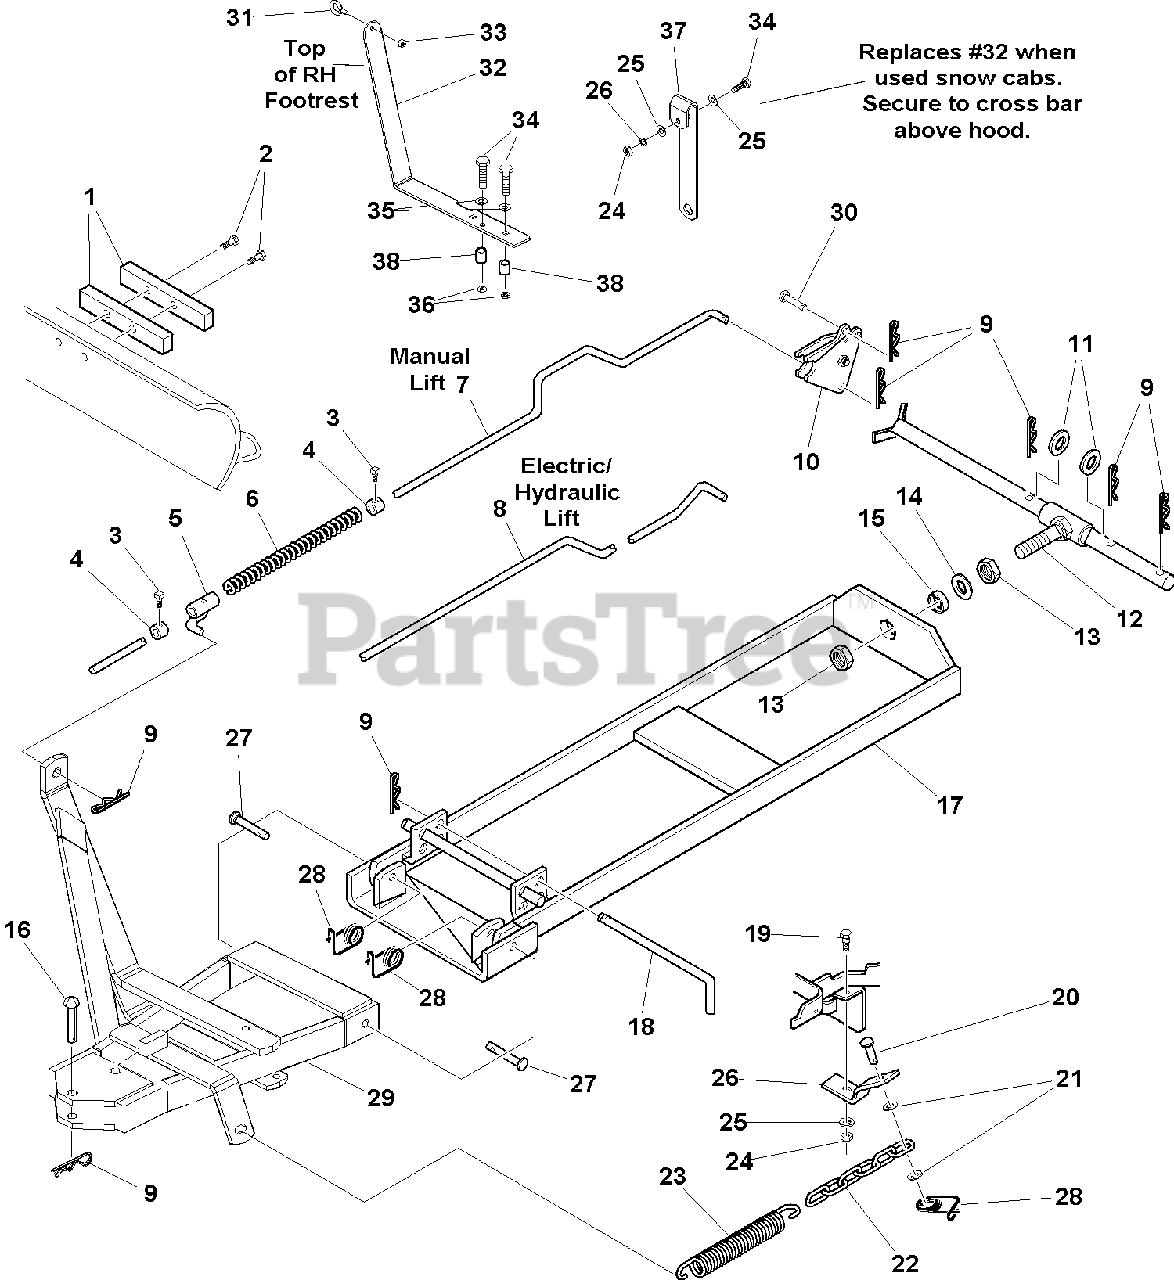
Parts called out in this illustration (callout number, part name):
1	BAR
2	CAPSCREW, Taptite, 5/16-18 x 1
3	SCREW, Set, 5/16-18 x 1/2
4	COLLAR
5	GUIDE ASSEMBLY
7	ROD, Manual Lift
8	ROD, Eletric / Hydraulic Lift
10	EXTENSION ASSEMBLY KIT
11	WASHER, 3/4
12	TUBE & BOLT ASSEMBLY
13	NUT, Hex, 5/8-11
14	WASHER, 5/8
17	REAR PUSH BAR ASSEMBLY
19	CAPSCREW, Hex Head 5/16-18 x 1
20	PIN
21	WASHER, 5/16
22	CHAIN, Link
24	NUT, Hex, 5/16-18
25	LOCKWASHER, 5/16
26	BRACKET
27	PIN
28	RETAINER, Pin
29	PUSH BAR ASSEMBLY
30	PIN, Round Head, 1/2 x 2-1/2
33	LOCKNUT, Hex, 1/4-20
34	CAPSCREW, Hex Head, 5/16-18 x 1-1/2
35	WASHER, 5/16
36	NUT, Centerlock, 5/16-18
37	BRACKET
